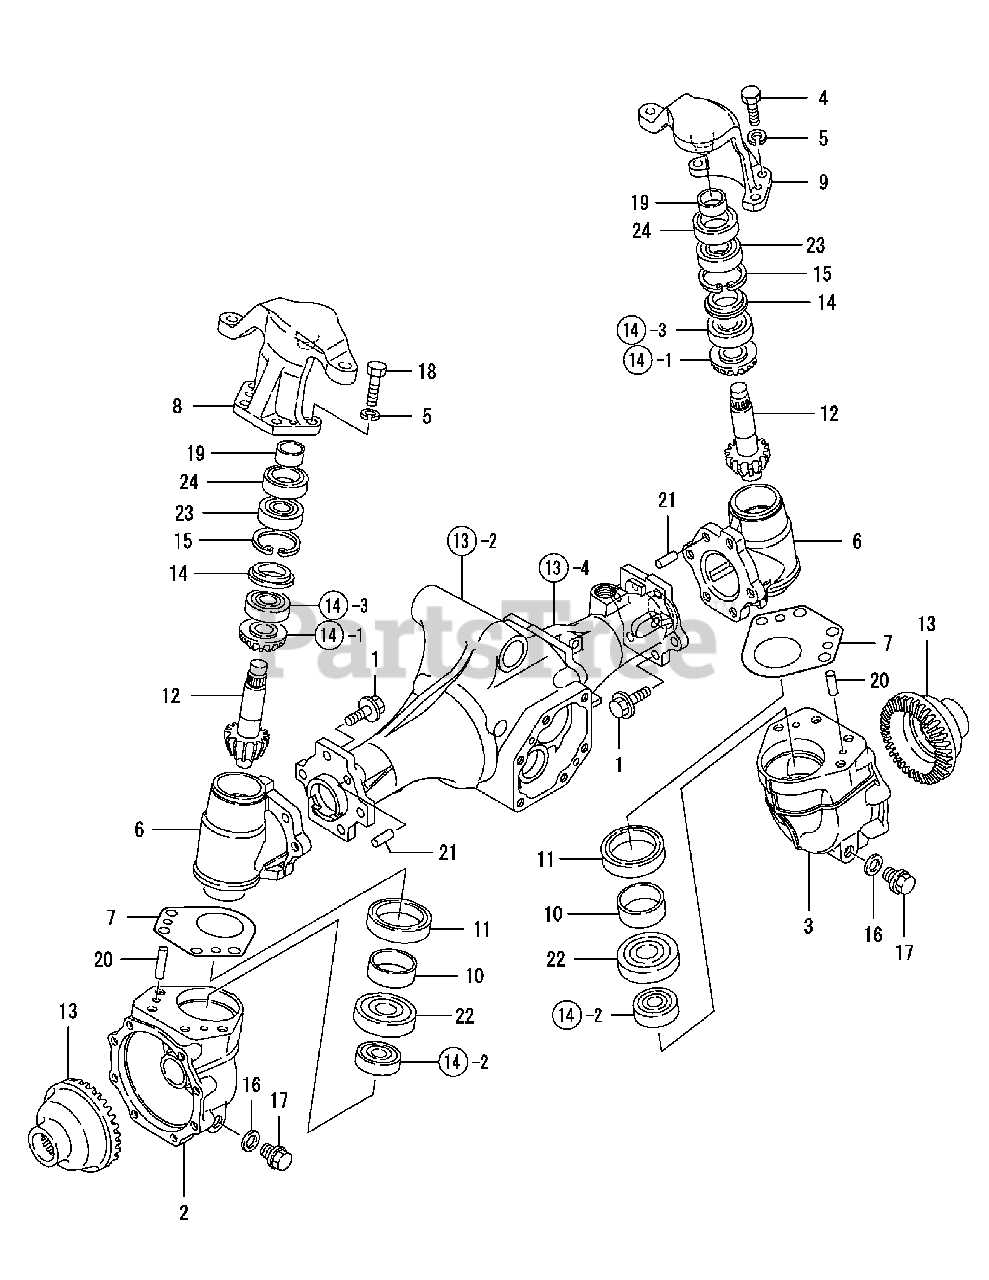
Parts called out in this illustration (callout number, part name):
2	Case, Final Gear L.H
3	Case, Final Gear R.H
5	Spring Washer 10
6	Case, Front Gear
8	Support, King Pin L
9	Steering Arm R.H.
10	Sleeve Si455016
11	Seal Tc6Y 506812.5
12	Pinion, Front Final
13	Fainal Gear, Front
16	Gasket(20*12*2
17	Bolt M 12X 12 Plated
19	Sleeve Si25X30X13
20	Parallel Pin, M8X20
21	Parallel Pin, M10X20
24	Seal Tc30 47 08, Oil
